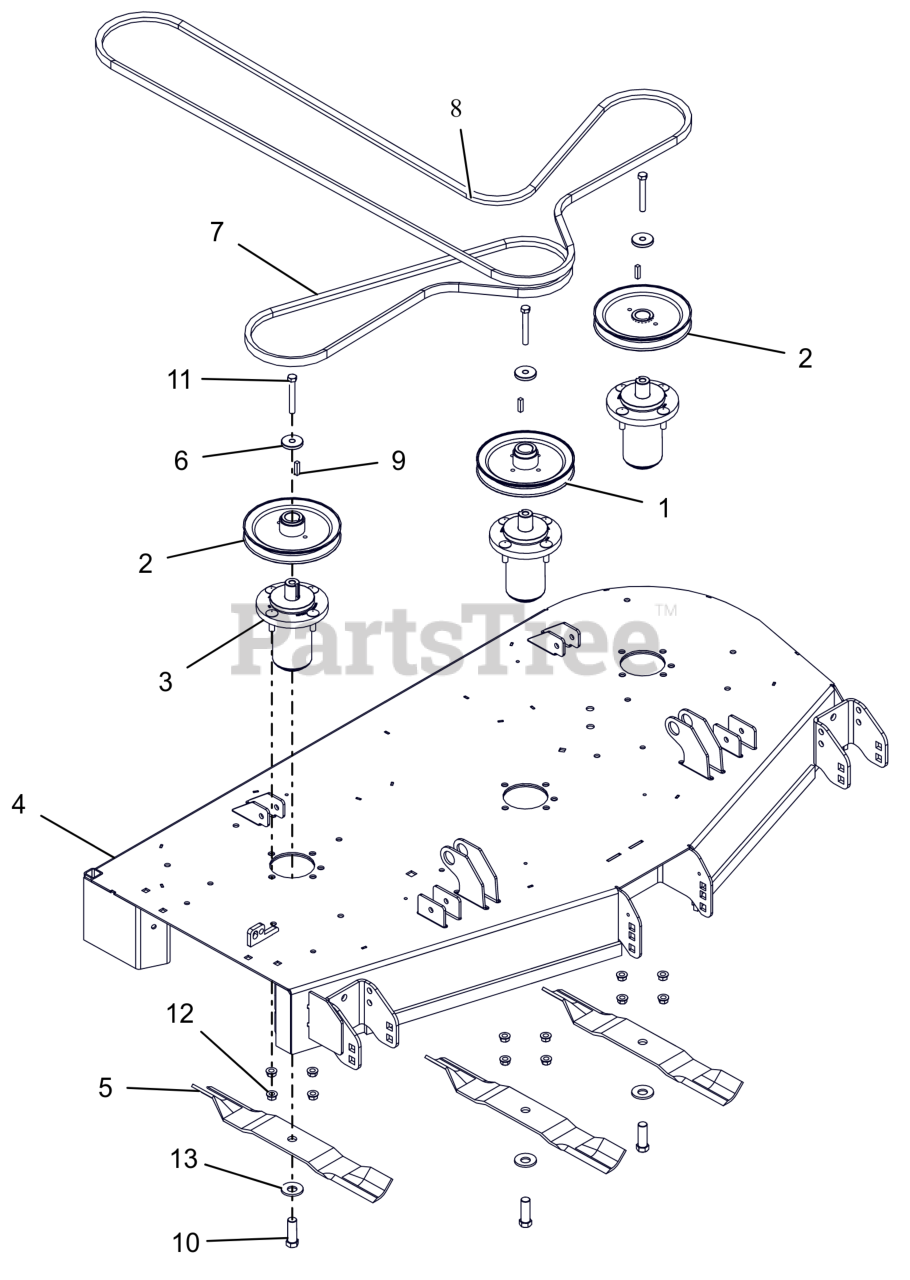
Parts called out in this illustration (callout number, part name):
1	PULLEY, DOUBLE-1"ID X 6.75"OD
2	PULLEY, V-1" ID X 6.75" OD
3	ASM, MAINT FREE ALUM SPINDLE
4	KIT,DECK-52" W/DECALS-ARIENSCE
5	BLADE, 18"
6	RETAINER, SHEAVE
7	V-BELT, B-COGGED
8	V-BELT, HB SECTION
9	KEY, SQ .25X.25X1.00 RC 40-50
10	BLT, HEX .62-18X1.75 G8 ZCC
11	BLT, HEX .38-16X2.75 G8 ZCC
12	NUT-LK-CTR-FLG .375-16 GF ZCC
13	WSHR-BLVL .669X1.535X.138
